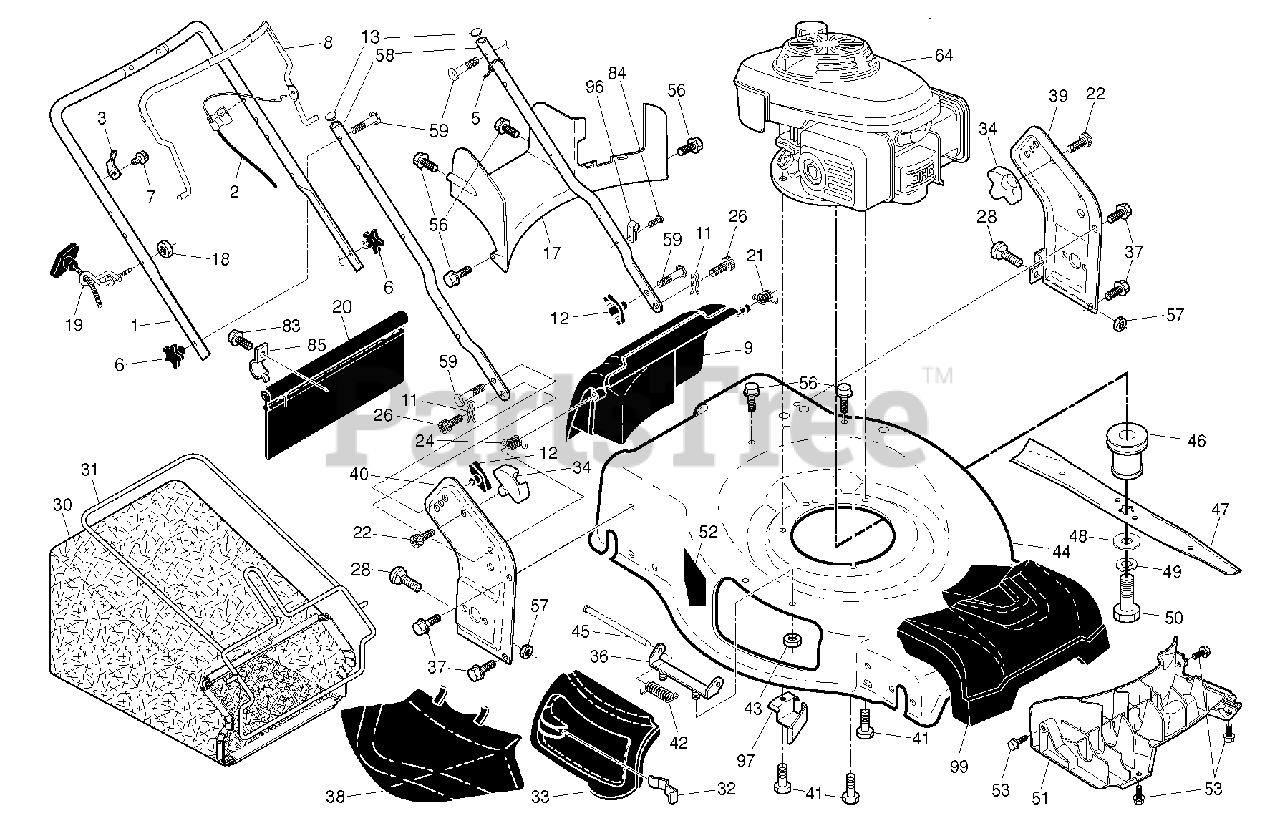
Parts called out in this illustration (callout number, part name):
1	HANDLE.UPPER.3.POS.BS.AW2.GREY
2	CABLE.MZR.50.SNAP-IN
3	BRACKET.UPSTOP.RT
5	TIE GUIDE
6	KNOB.HANDLE.PLASTIC.STAR.BLACK
8	BAIL.OVER.MOLD.ERGO.MZR.ORANGE
9	DOOR.REAR.ASM.22+.HUSQ.FG/RGD
11	COTTER.HAIRPIN.DOOR/HANDLE.PIV
12	KNOB, DEFLECTOR
13	PLUG.PLASTIC.7/8".14-20.GAUGE
17	BAFFLE.REAR.22+RGD.AWD.PLASTIC
18	NUT
19	RB GUIDE.ROPE.STD.BLK.ZIN WSL
20	SKIRT.REAR.22PLUS.RGD.LW(2 2MC
21	SPRING.LH.BLACK
22	SCREW.PAN.HEAD.#10
24	SPRING.RH.GRAY
26	SCREW,DOOR/HANDLE.PIVOT
28	BOLT
30	GBAG.B5610247T.SIL.HUSQ.BLUE
31	RB FRAME.GBAG.22PLUS
32	LATCH.DOOR.ZINC
33	DOOR.MULCH.22 PLUS.HUSQ.GREY
34	BRACKET.GRASSBAG.ATTACHING.BLK
36	BRACKET.ASM.HINGE.21.FWGD.
37	BOLT.5/16HEX.WHS.HD
38	DEFLECTOR.CLIPPING.22.BLACK
39	BRACKET.ASM.HNDL.LT.22+.GREY
40	BRACKET.ASM.HNDL.RT.22+.GREY
41	BOLT 3/8-16X1-1/8
42	SPRING.TORSION
43	NUT.HEX.FLANGE.1/4
44	HOUSING.22+.RWD.HUSQ.ORANGE
45	ROD.HINGE.21
46	ADAPTER.BLADE.25MM.3MPH
47	BLADE 22 4-N-1 2PIN 5STAR BLK
48	WASHER,HARDEN
49	LOCKWASHER
50	SCREW, HEX HD 3/8-24 X 1-3/8
51	BAFFLE.FRONT.22+PLASTIC.(2 2)
52	DANGER DECAL
53	SCREW.HI-LO.5/16 X.75
56	SCREW.HX.13X.750
57	NUT.FLANGE.5/16
58	HANDLE.LOWER.22+BT.2PC.GRY
59	BOLT, HANDLE 5/16-18X1.75
83	TAPPING SCREW
84	FASTENER.PUSH.O.250X0.783
85	BRACKET.SKIRT.22+.BZP
96	CLIP.CABLE.BLK
97	BRACKET.BELT.GUIDE.22+.BZP
99	COVER.ASM.FRONT.SHROUD.HUSQ.
